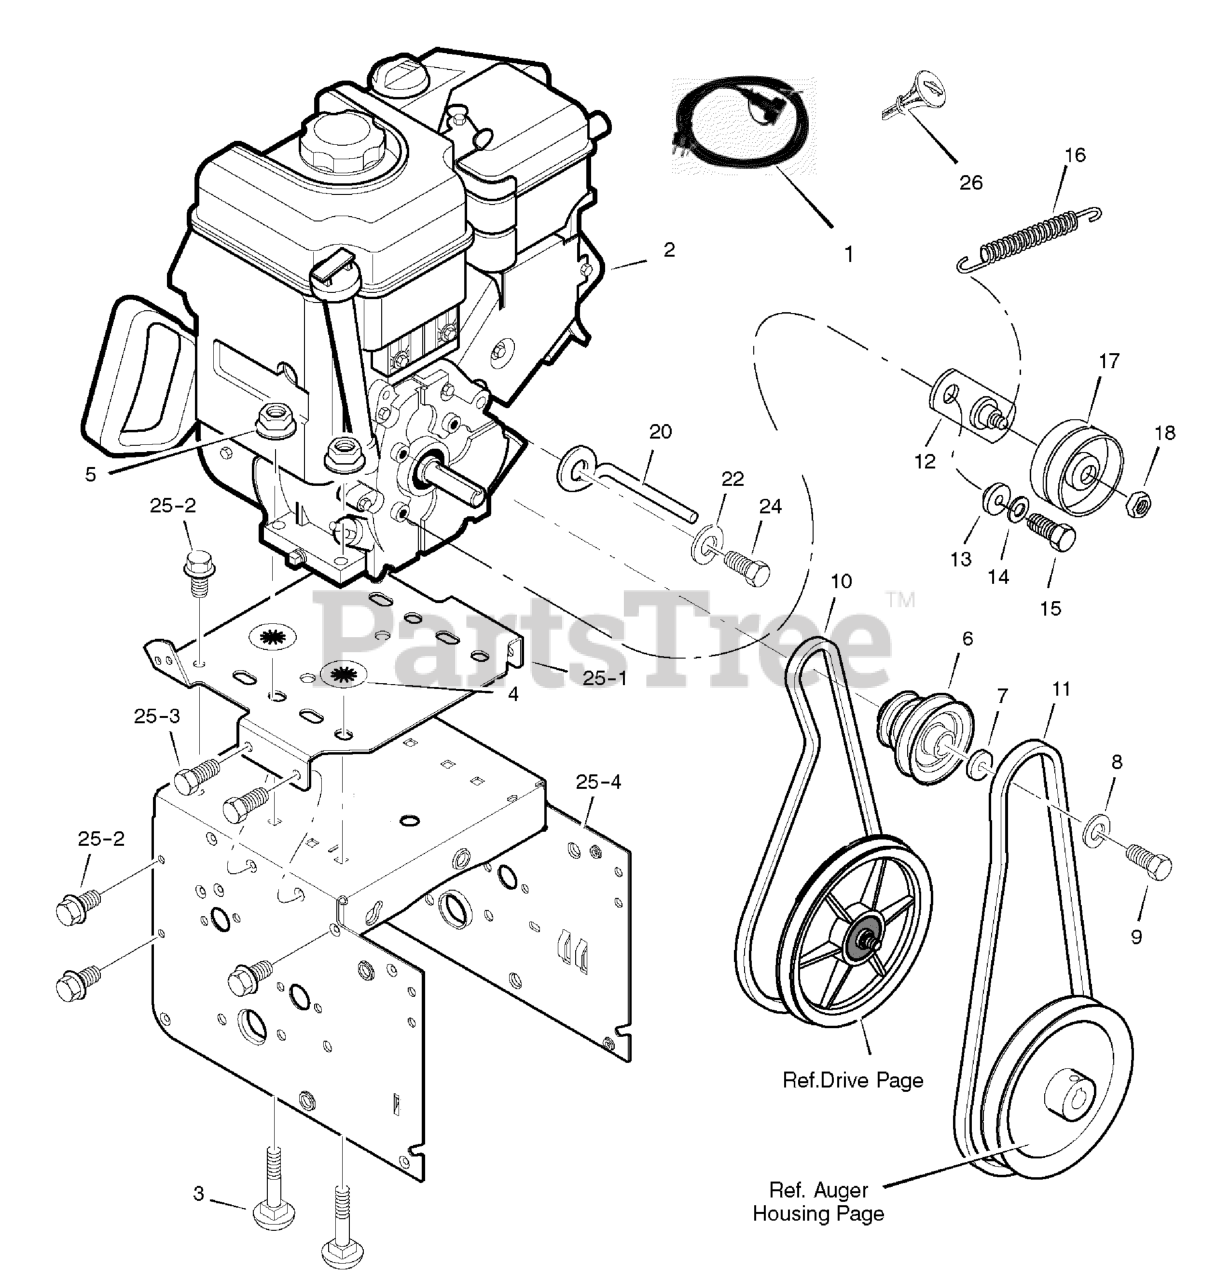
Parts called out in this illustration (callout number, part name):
1	CORD, STARTER
2	ENGINE
3	BOLT, CARRIAGE
4	RETAINER, PUSH
5	NUT
6	PULLEY, ENGINE
8	WASHER
10	V-BELT, 3L, 33.13
11	V-BELT, 4L, 38.35
12	BRACKET ASSEMBLY, IDLER
13	BUSHING, IDLER BRACKET
14	WASHER, SPLIT
15	SCREW 5/16-24 X 0.75
16	SPRING, IDLER TRACTION DRIVE
17	PULLEY, IDLER
18	NUT, JAM 3/8-16
20	GUIDE, ROD BELT
22	WASHER
25	FRAME ASSEMBLY
25-1	PLATE, ENGINE MOUNT
25-2	SCREW
25-4	FRAME, MOTOR BOX
26	KEY, BRIGGS ENGINE
